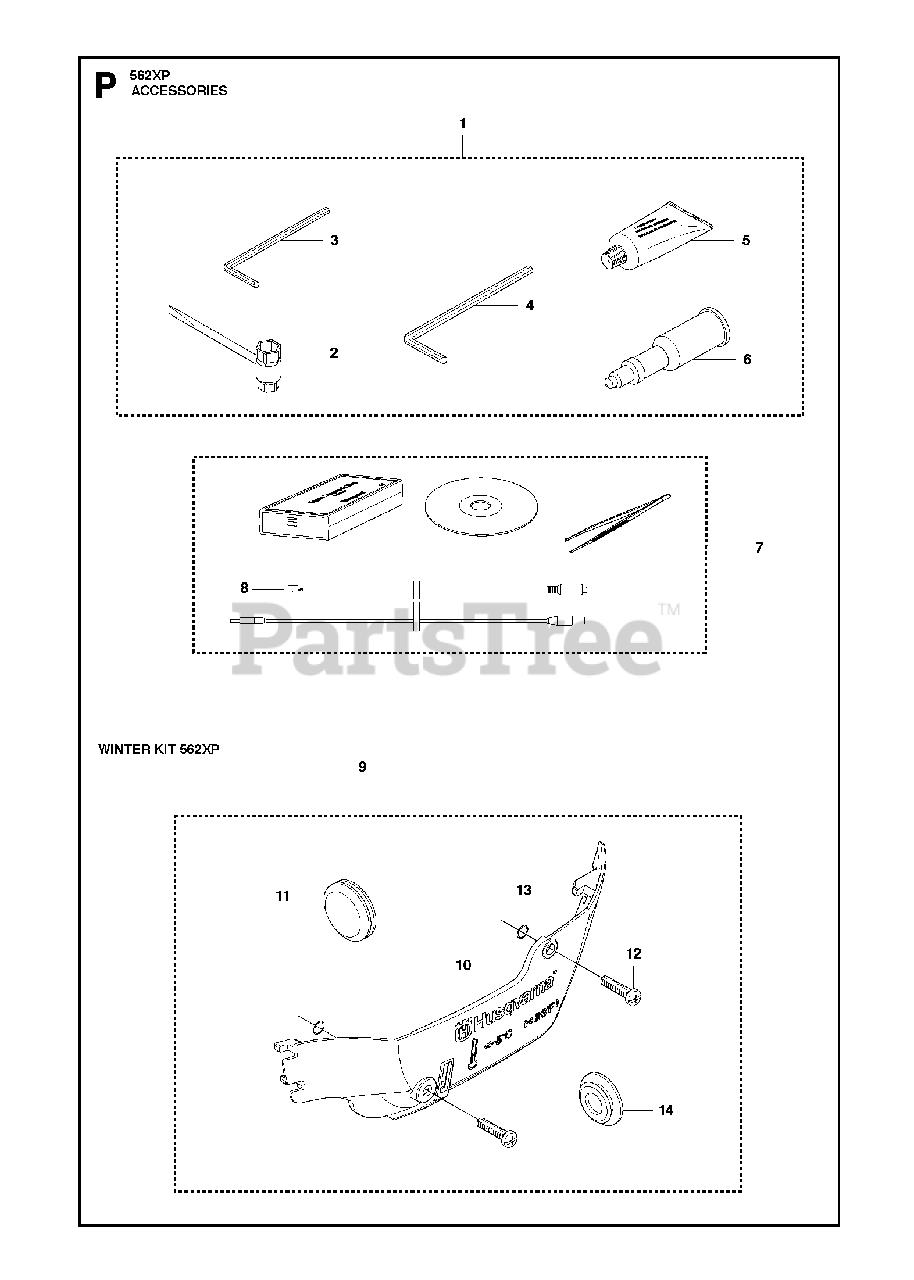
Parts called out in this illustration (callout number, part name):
2	COMBINATION WRENCH
3	L-SPANNER
4	L-SPANNER
5	GREASE
6	Grease Gun
7	SERVICE TOOLS
8	CABLE ASSY
9	WINTER KIT
10	WINTER COVER
11	PLUG
12	SCREW
13	O-RING
14	WINTER PLUG
